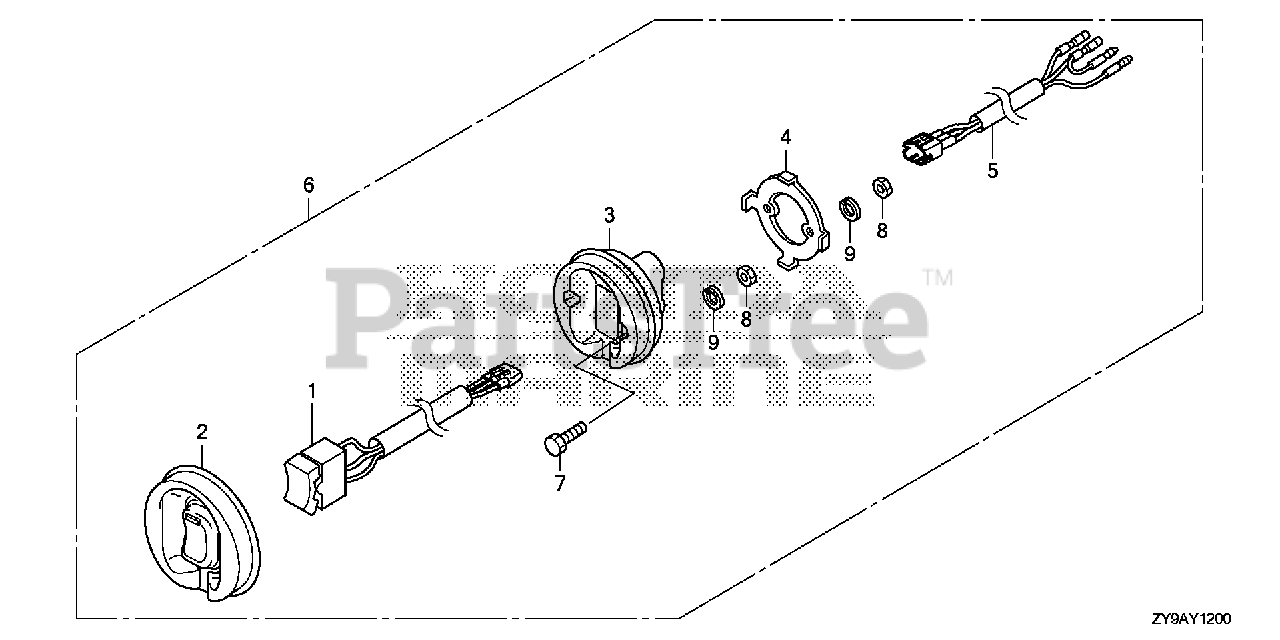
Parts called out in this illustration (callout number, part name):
1	SWITCH ASSY., TROLLING CONTROL
2	RUBBER, TROLLING CONTROL SWITCH PANEL
3	BODY, TROLLING CONTROL SWITCH PANEL
4	BRACKET, TROLLING CONTROL SWITCH PANEL
5	HARNESS, TROLLING CONTROL SWITCH PANEL
6	PANEL ASSY., TROLLING CONTROL
7	BOLT, HEX. (4X20)
8	NUT, HEX. (4MM) (NOT AVAILABLE)
9	WASHER, SPRING (4MM)
